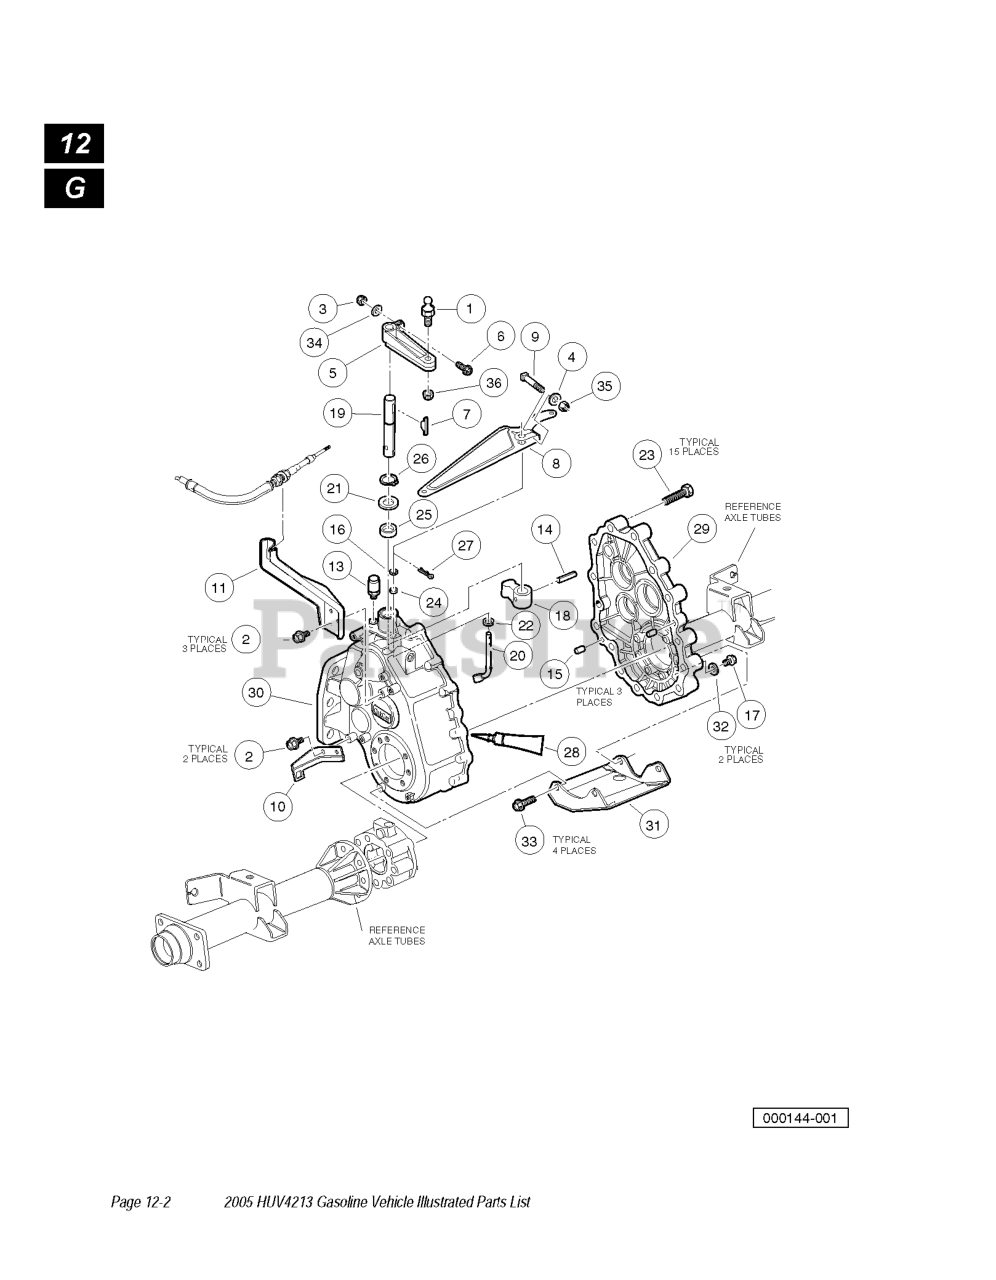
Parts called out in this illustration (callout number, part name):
2	SCREW HX TYP TT
5	TRANSMISSION SHIFT LEVER
6	SCREW, #1--32 X .75 HX HD MACH
7	KEY, WOODRUF
8	ARM, GOVERNOR
9	SCREW, 1/4-20 X 1.00 SQ HEAD
10	DIFFERENTIAL LOCK BRACKET
11	SHIFTER BRACKET
12	TRANSAXLE, HD, 15.51 RATIO
16	WASHER, M6 FLAT
17	PLUG, DRAIN FE290D
18	LEVER - CHANGE
19	SHAFT-CHANGE
23	SCREW, M8-1.25 X 40MM HEX HEAD
26	RING, INTERNAL RETAINING
27	PIN, COTTER
28	SEALANT
29	GEAR CASE, RIGHT
30	GEAR CASE, LEFT
31	GUARD, TRANSAXLE
34	WASHER FLAT
35	LOCKNUT, 1/4-20 NYLON INSERT
36	LOCKNUT, 1/4-28 NYLON INSERT
